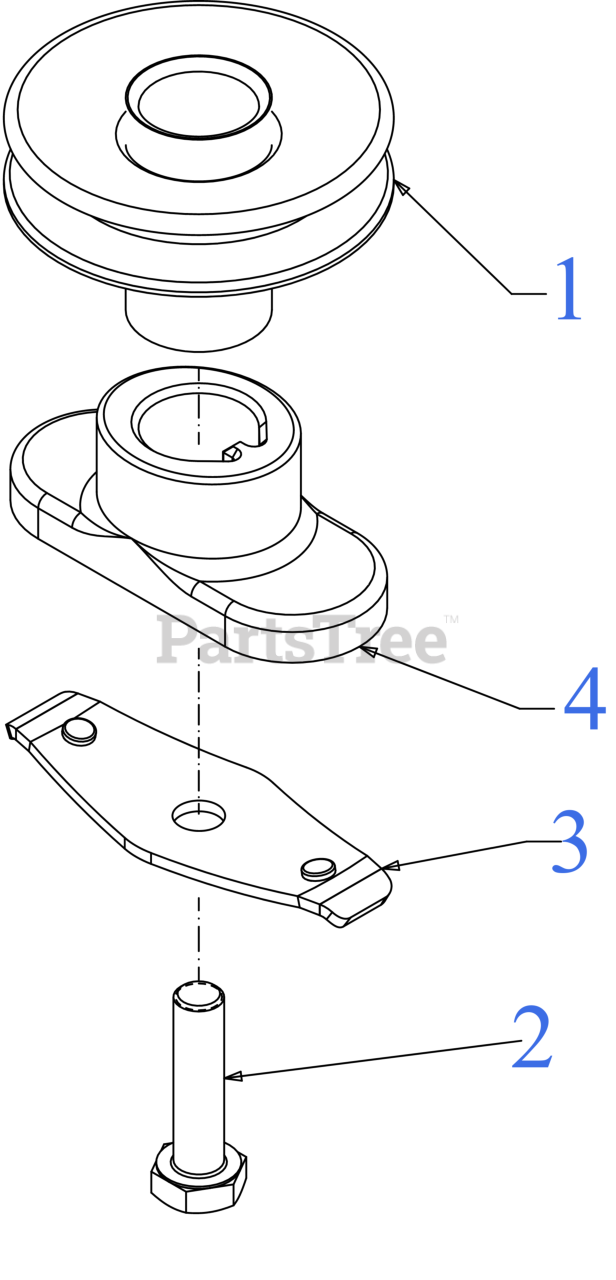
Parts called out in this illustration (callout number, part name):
1	ADAPTER (7/8" VARI 2.66 )
2	SCREW 3/8-24 x 1.50 GR8
3	BLADE BELL SUPPORT
4	BLADE ADAPTER (#6 X 1.19 W/S)
